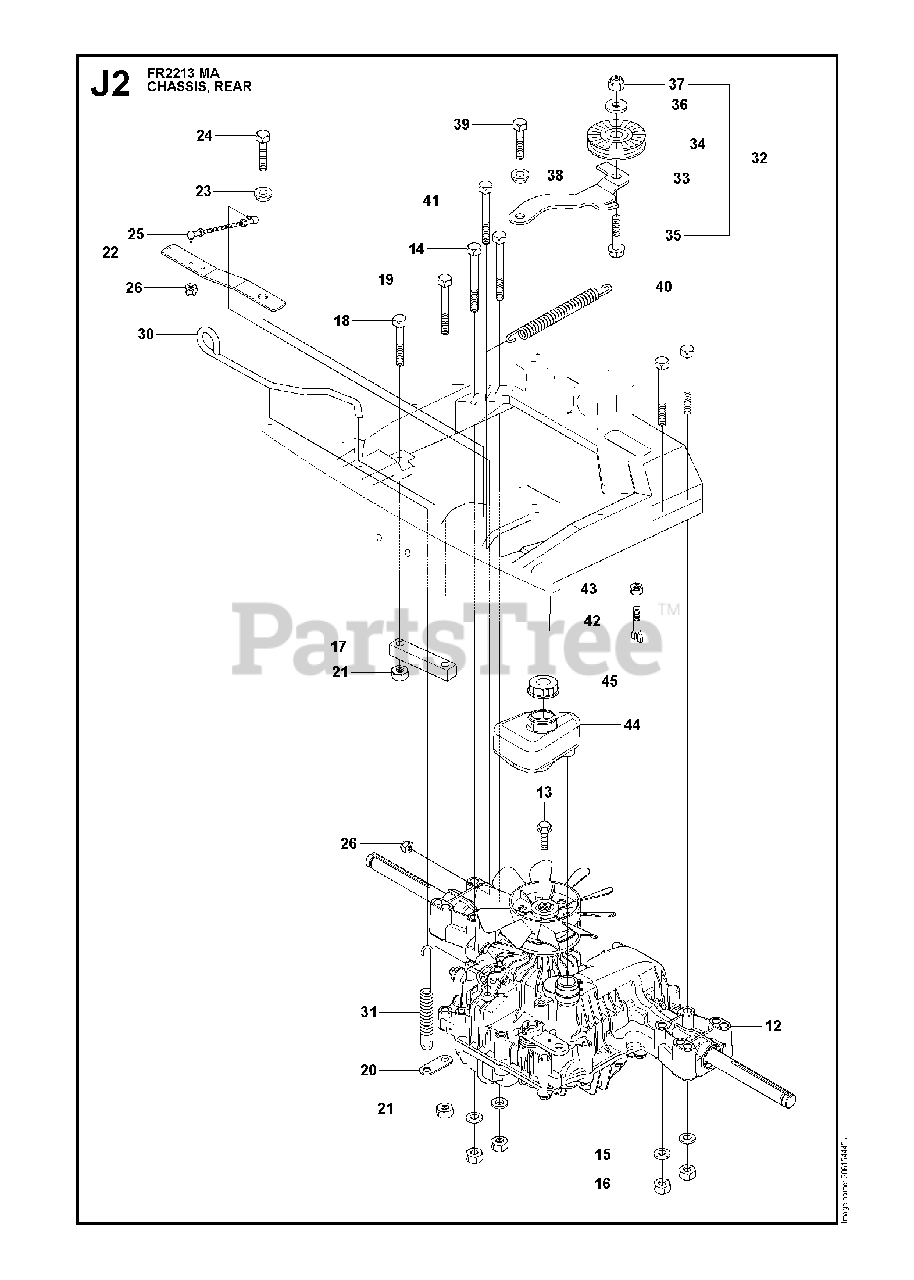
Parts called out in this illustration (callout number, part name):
2	BALL BEARING 6005-2RS
3	BALL BEARING 6010 2RS1
4	CIRCLIP SGH 47
5	RETAINING RING SGA 25
6	SHAFT
7	RETAINING RING SGA 25
8	WASHER
9	V-RING
11	BUSHING
12	HYDROSTAT
13	BOLT
14	HEX BOLT
15	WASHER BRB 8.4X17
16	NUT
17	BRACKET
18	SCREW
19	SCREW
20	CONNECTOR
21	NUT
22	ARM
23	WASHER
24	SCREW 8X20
25	ROD
26	LOCKNUT M5
27	BRACKET
28	CLAMP
29	SCREW
30	ROD
31	SPRING
32	TENSIONER
33	TENSIONER
34	PULLEY
35	SCREW
36	SPACER
37	LOCKNUT M8
38	WASHER
39	SCREW 8X20
40	SPRING
41	SCREW
42	SCREW
43	NUT
44	TANK
45	TANK CAP
46	DRAW RING
47	SCREW M10X25
